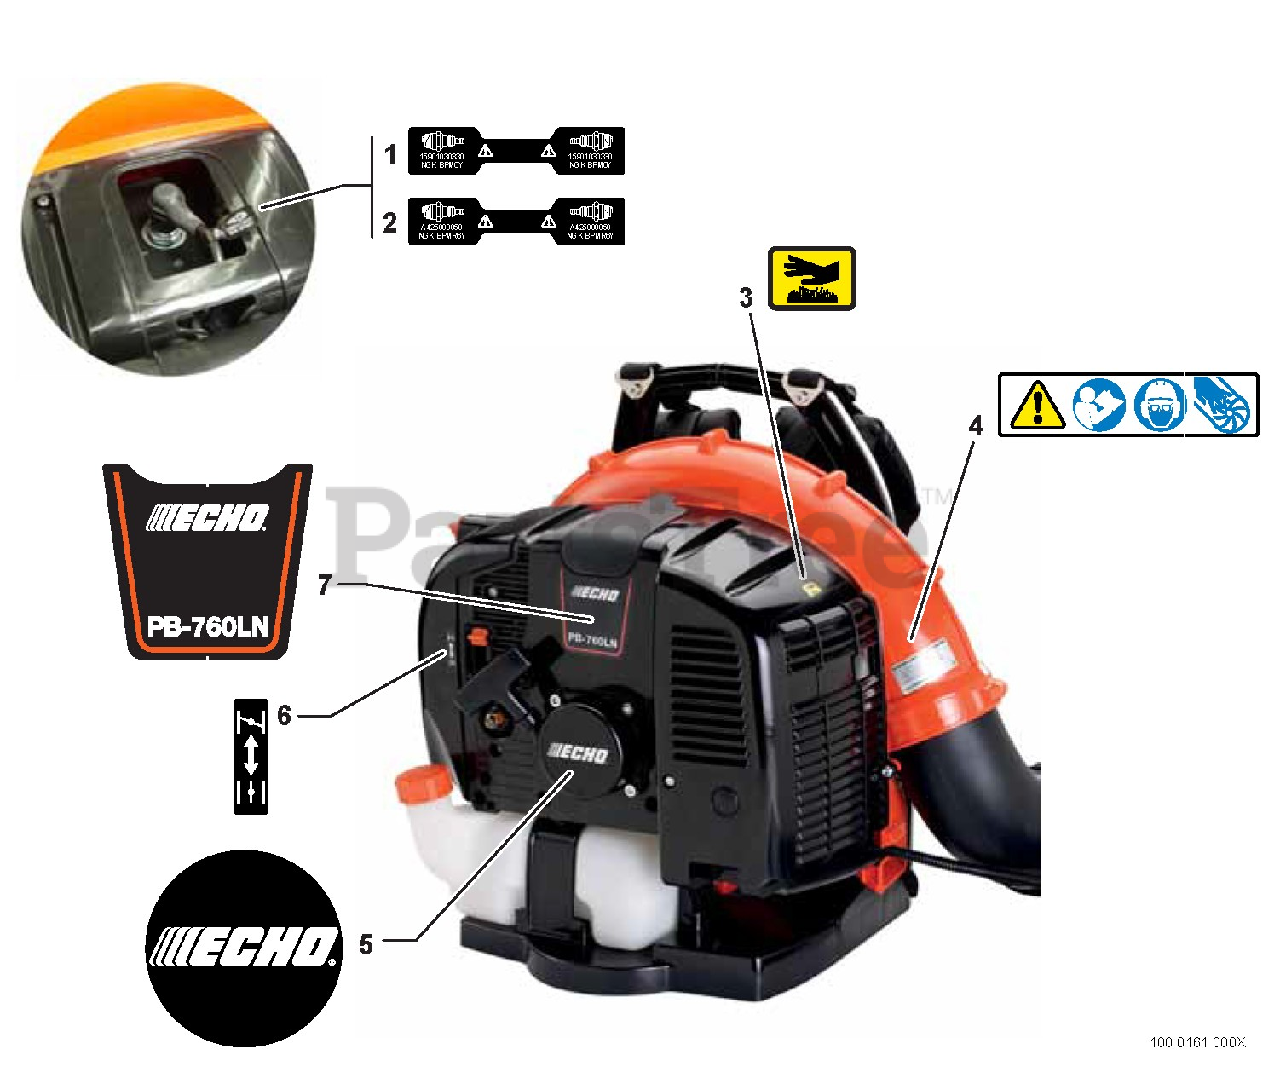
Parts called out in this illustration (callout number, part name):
1	LABEL - SPARK PLUG -- BPM-6Y
2	LABEL - SPARK PLUG -- BPMR-6Y
3	LABEL - HOT SURFACE
4	LABEL - CAUTION
5	LABEL - ECHO
6	LABEL - CHOKE
7	LABEL - MODEL PB-760LN
